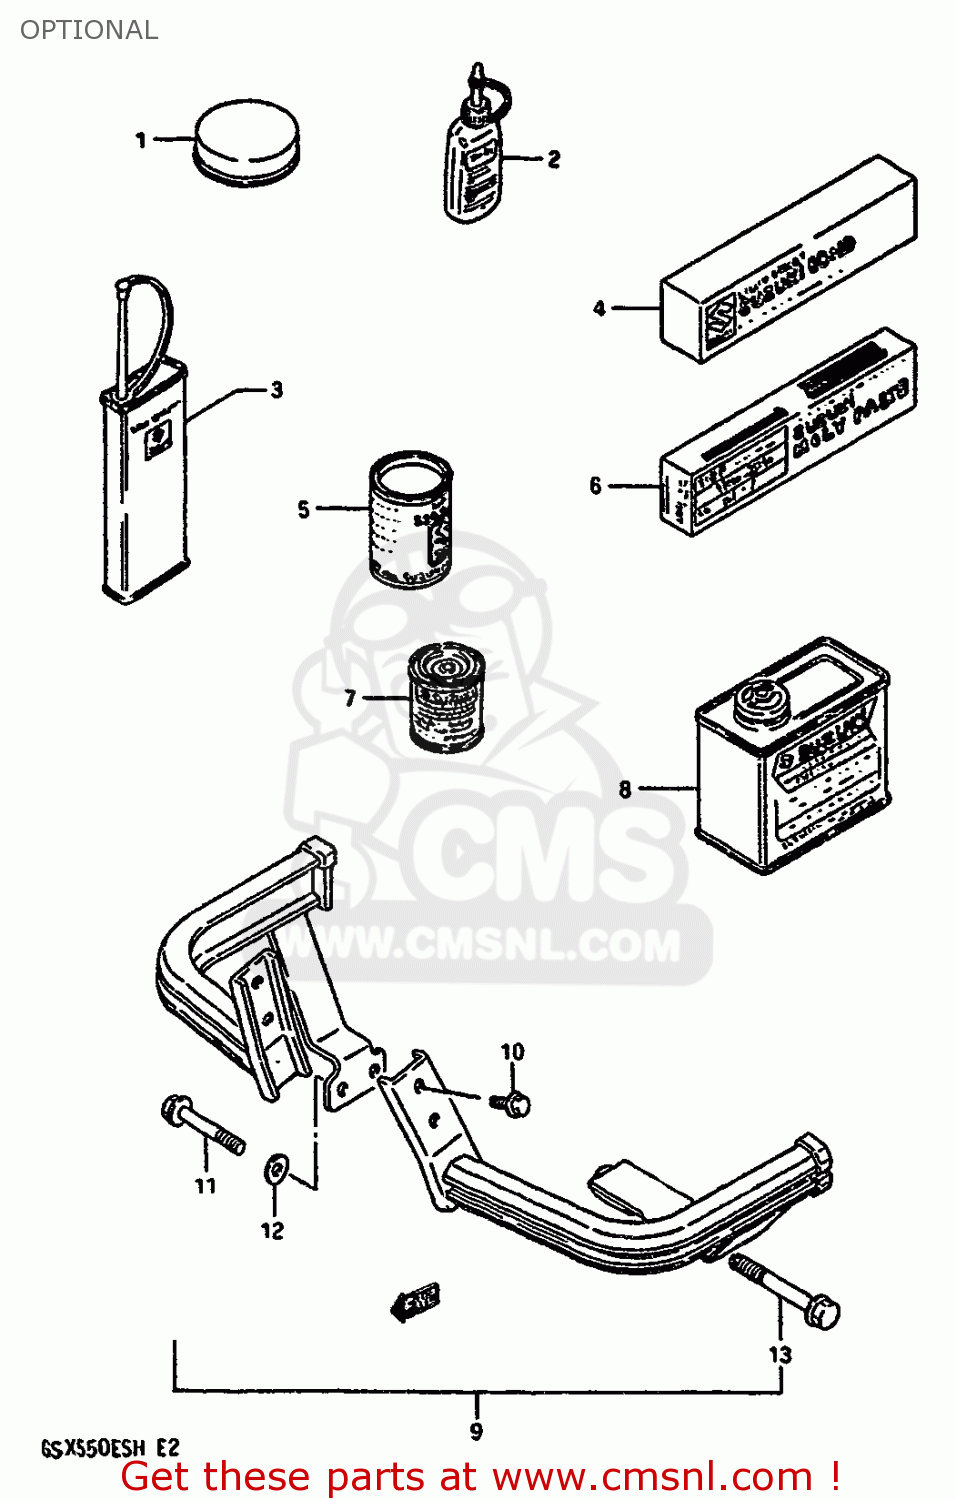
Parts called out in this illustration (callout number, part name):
1	GREASE,PBC FOR BRK PAD 20G
2	THREAD LOCK NO.1342
3	THREAD LOCK NO.1401 CLEAR 200G
4	LIQUID GSKT NO.1207B 100G BLK
5	GREASE(C)EP2 LITHIUM 150G
6	SUZUKI MOLY PASTE
7	PAINT,BLACK
8	PAINT (MEDIUM GOLD)
9	BAR SET,ACCESSORY
10	BOLT
11	BOLT
12	WASHER (8.5X24X2.3)
13	BOLT,LH
